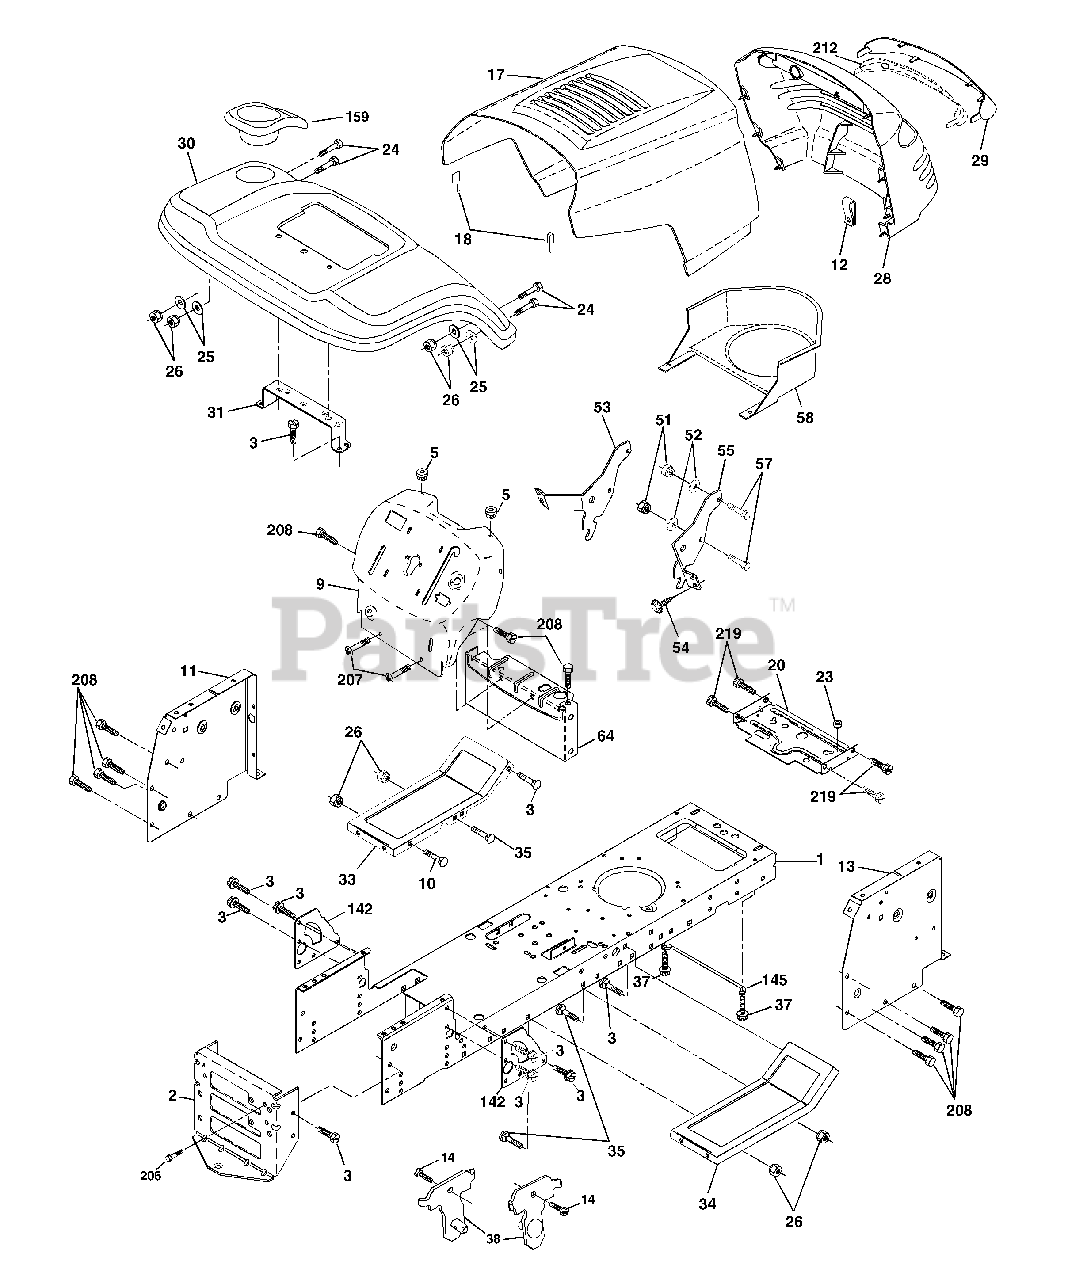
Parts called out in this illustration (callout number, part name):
1	Chassis
2	Drawbar
3	Screw 3/8-16 X .75
5	Bumper Hood/Dash
9	Dash P/L
10	Bolt Carriage 3/8-16 x 1
11	Panel Dash Lh
12	Clip Tinnerman
13	Panel Dash Rh
14	Screw Thdrol 3/8-16 x 1/2
17	Hood LT/PL
18	Bumper Hood
20	Plate Mtg Battery Fuel Tank
23	Bushing
24	Bolt Fin Hex 3/8-16 x 1 Gr 5
25	Washer 13/32 X 13/16 X 12 Ga
26	Nut Lock Hex W/Ins 3/8-16 Unc
28	Grille/Lens Asm
29	Lens LT/PL
30	Fender Footrest STLT Pnt
31	Bracket Fender
33	Footrest Pnt Lh
34	Footrest Pnt Rh
35	Bolt Rdhd Sht Sqnk 3/8-16 x 3/4
37	Screw Thdrol 6/16-18 x 1/2 TYT
38	Bracket Asm Pivot Mower Rear
51	Nut Lock Hex W/Ins 1/4-20
52	Washer 9/32 x 7/8 x 16 Ga.
53	Bracjet Grukke Lh
54	Screw Hex Wshd 8-18 x 7/8
55	Bracket Grille Rh
57	Bolt Hex 1/4-20 x 3/4
58	Duct Air
64	Dash Lower STLT
142	Plate Reinforcement STLT
145	Rod Pivot Chassis/Hood
159	Cupholder
206	Bolt Shoulder 5/16-18
207	Screw Thdrol 5/16-18 x 1/2
208	Screw Thdrol 3/8-16 x 1/2
212	Insert Lens Relect
219	Screw 5/16-18 x 3/4
